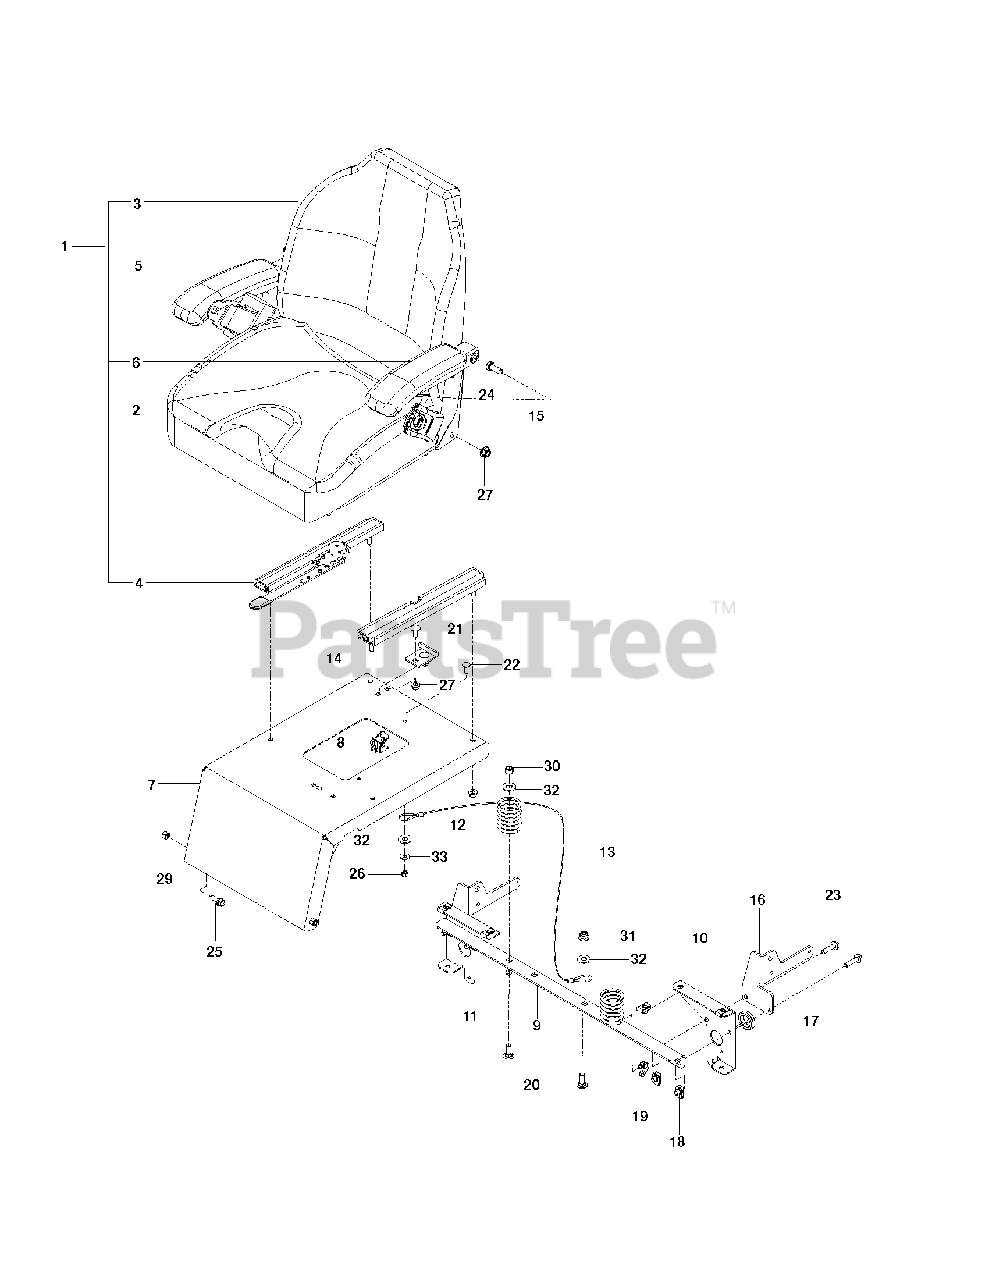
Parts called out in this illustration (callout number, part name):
2	ASSEM, CUSHION
3	ASSEM.BACK.SEAT
4	4"SINGLE LOCK TRACK SET W/HDWR
5	BLACK SELFSKIN-ARM PAD ONLY
6	LEFT SELFSKINNED 907 ARM W/BRK
8	SEAT SWITCH
9	SUPPORT, SEAT
10	SUPPORT, LT, BLK
11	SUPPORT, RT, BLK
13	SEAT LANYARD
14	STOP, SEAT - BLACK
16	MOUNT, SEAT BELT, BLACK
18	U-CLIP 5/16-18 NUT RETAINER
19	TIE WRAP, 8-3/8", W/CLIP
20	RHSNB 3/8C X 1
21	RHSNB 5/16-18 X 3/4
22	RHSNB 1/4C X 3/4
23	HHFS 5/16-18 X 1.25 TPBLT GD 5
24	HCS 7/16-20 X .75 GD 5
25	SB 5/16-18 HEX HD GD5, BLK ZN
26	NUT 1/4-20 NYLOC
27	NUT HEX 7/16F LOCK RP
28	5/16-18 NYLOC FLANGE NUT
29	NUT 5/16 NYLOC
30	NUT 3/8-16 NYLOC
31	NUT 3/8-16 HEX FLG NYLOC ZD
32	WASHER 3/8 FLAT
33	WASHER 1/4 FLAT
